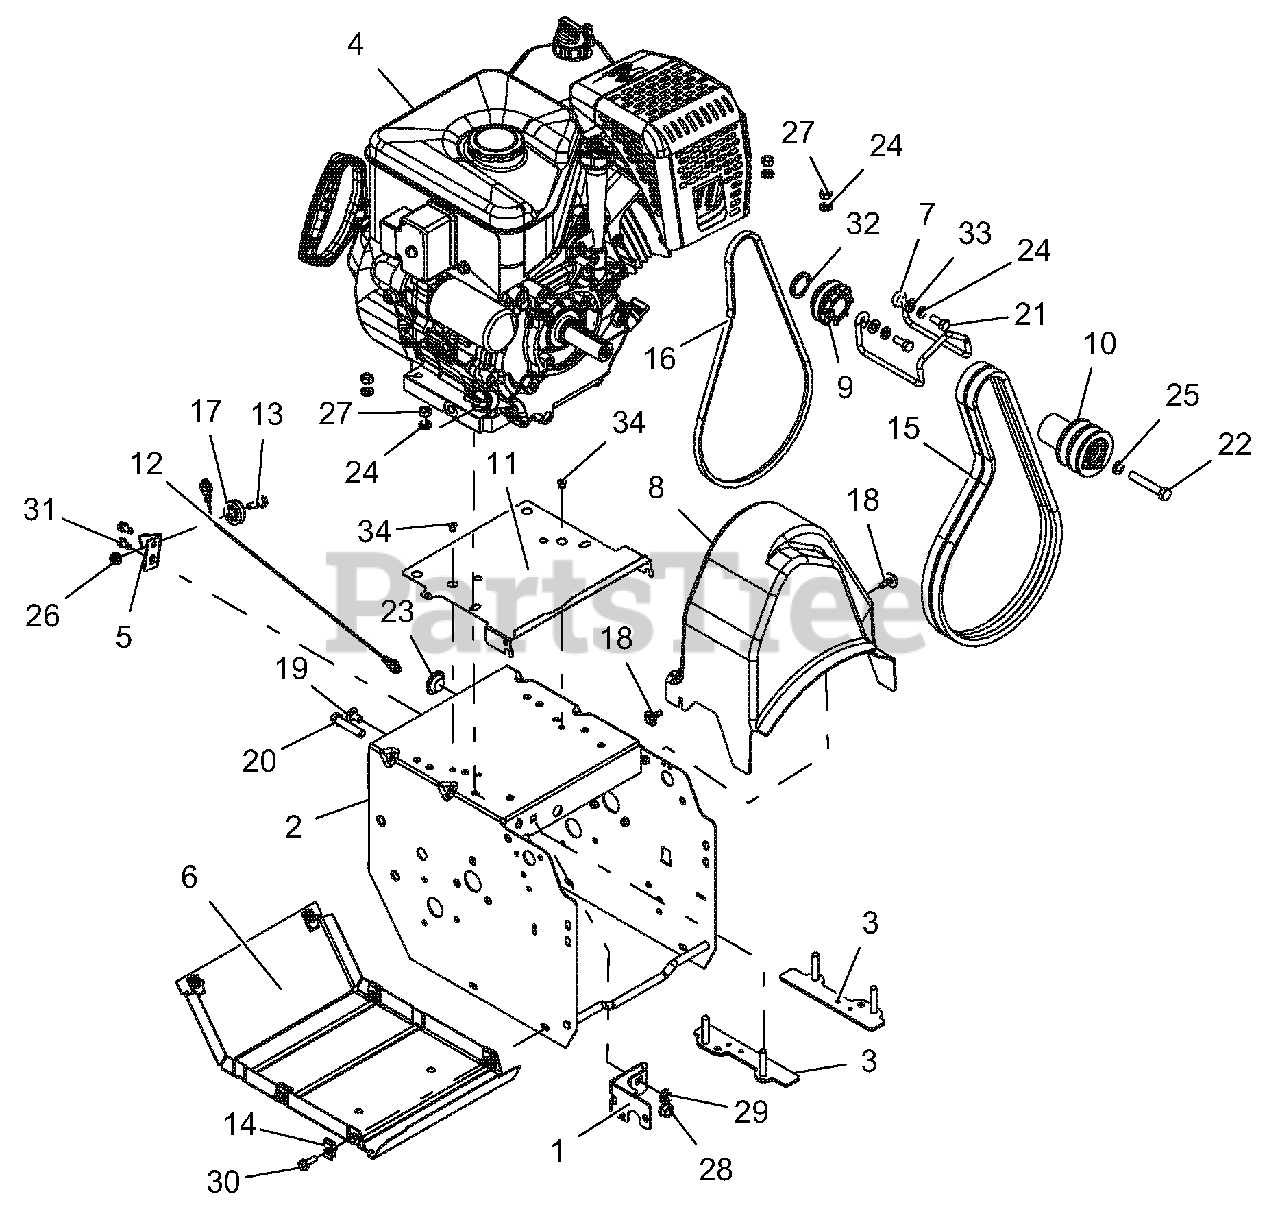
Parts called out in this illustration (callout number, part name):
1	WELDMENT, FRAME BRACKET
2	WELDMENT, FRAME - DELUXE 16"
3	STRAP,ENGINE BOLT,ARIENS LRG
4	ENGINE, AX369 GEN 3 120V/60W
5	BRACKET, CABLE PULLEY
6	COVER, BOTTOM
7	FINGER, BELT
8	BELT COVER
9	SHEAVE, DRIVE
10	SHEAVE,ATTACHMENT 2-GRV
11	BAFFLE,ENGINE,ARIENS LRG BLOCK
12	CABLE, LOWER TRACTION (DELUXE)
13	BOLT, SHLDR-.375X.375X.25-20
14	NUT-RTNR .25-20X.56
15	V-BELT, HA-RAW EDGE (SET)
16	V-BELT, 3L-RAW EDGE
17	PULLEY, CABLE
18	SCR-TAP .25-20X.5 CAPTIVE
19	@BLT-RHDSSQNK .31-18X.62 G5YZ
20	@BLT-HEX .38-16X1.75 GR5 YWZC
21	BLT-HEX .31-24X.75 YWZC GR5
22	BLT-HEX .38-24X2.25 YWZC GR5
23	PLUG, HOLE - .875" NYLON
24	WSHR-LK .312X.097 HVY YWZC
25	@WSHR-LK .38X.094 REG YWZC
26	@NUT-LK-CTR-FLG .25-20 YWZC
27	@NUT-HEX .31-18 YWZC
28	@NUT-LK-TOP-FLG .38-16 YWZC
29	@NUT-LK-TOP-FLG .31-18 YWZC
30	BLT-HEX .25-20X.75 HWH YZ GR5
31	SCR-TAP .25-20X.50 HWH TR YWZ
32	WSHR-FL-NYL 1.03 X 1.31 X .134
33	@WSHR-FL-STL.344X.688X.065YWZC
34	RVT-POP .187 YZ
